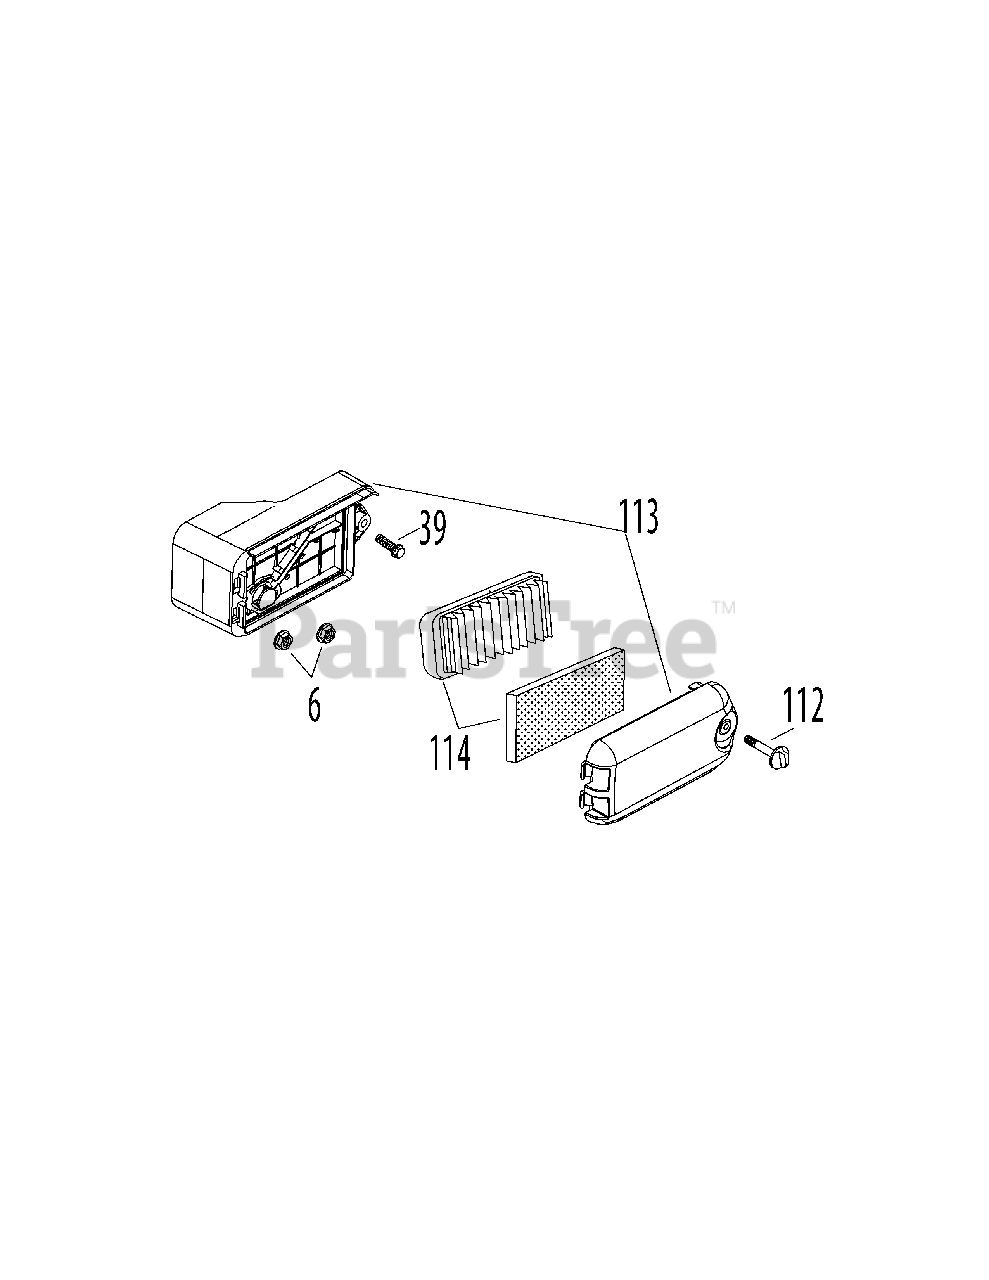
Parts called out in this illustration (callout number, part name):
6	Nut M6 X 10 Mm
39	Bolt M6×30
112	Air Filter Cover Thumb Screw
113	Air Cleaner Housing Ass'y Comp
114	Air Cleaner Kit
